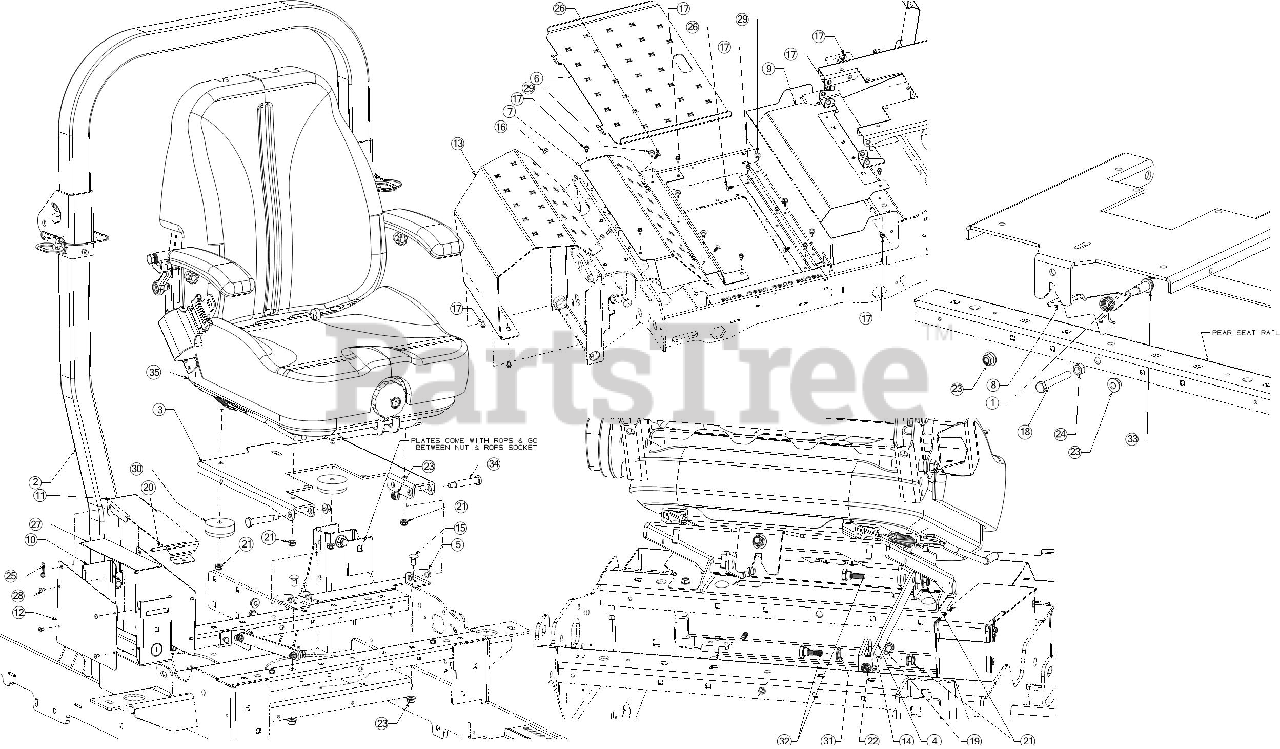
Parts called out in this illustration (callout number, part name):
1	HANDLE SPRING (LH)
2	ROPS ASSEMBLY
3	SEAT MOUNT BRACKET
4	SEAT LOCKOUT BRACKET
7	FLOOR PANEL
8	SEAT LATCH LEVER
10	STORAGE TOOLBOX
11	STORAGE TOOLBOX LID
12	SIDE PANEL BOX
13	FRONT PANEL COVER
14	SEAT LOCKOUT MOUNT
15	CARRIAGE BOLT 3/8-16 x .750 GR5
16	SCREW 1/4-20 x .5
17	SCREW 1/4-20 X.500
18	HEX SCREW-3/8-16X2.5 GR5
19	SCREW 1/4-20X.75 GR5
21	FLANGE LOCK NUT 5/16-18
22	FLANGE LOCK NUT
24	HEX NUT
25	BOW TIE COTTER PIN 1/4-5/16
26	RATCHET CLIP .250
27	ADHESIVE PAD
28	FULL TUBULAR RIVET
29	BUMPER, .62 DIA x .3
30	RUBBER BUMPER
31	FLAT WASHER .469X.750X.054
32	SHOULDER SCREW .437
33	SHOULDER SCREW .50X.925
34	SHOULDER SCREW .50 x 2.23 3/8-16
35	SEAT (COMMERCIAL)
